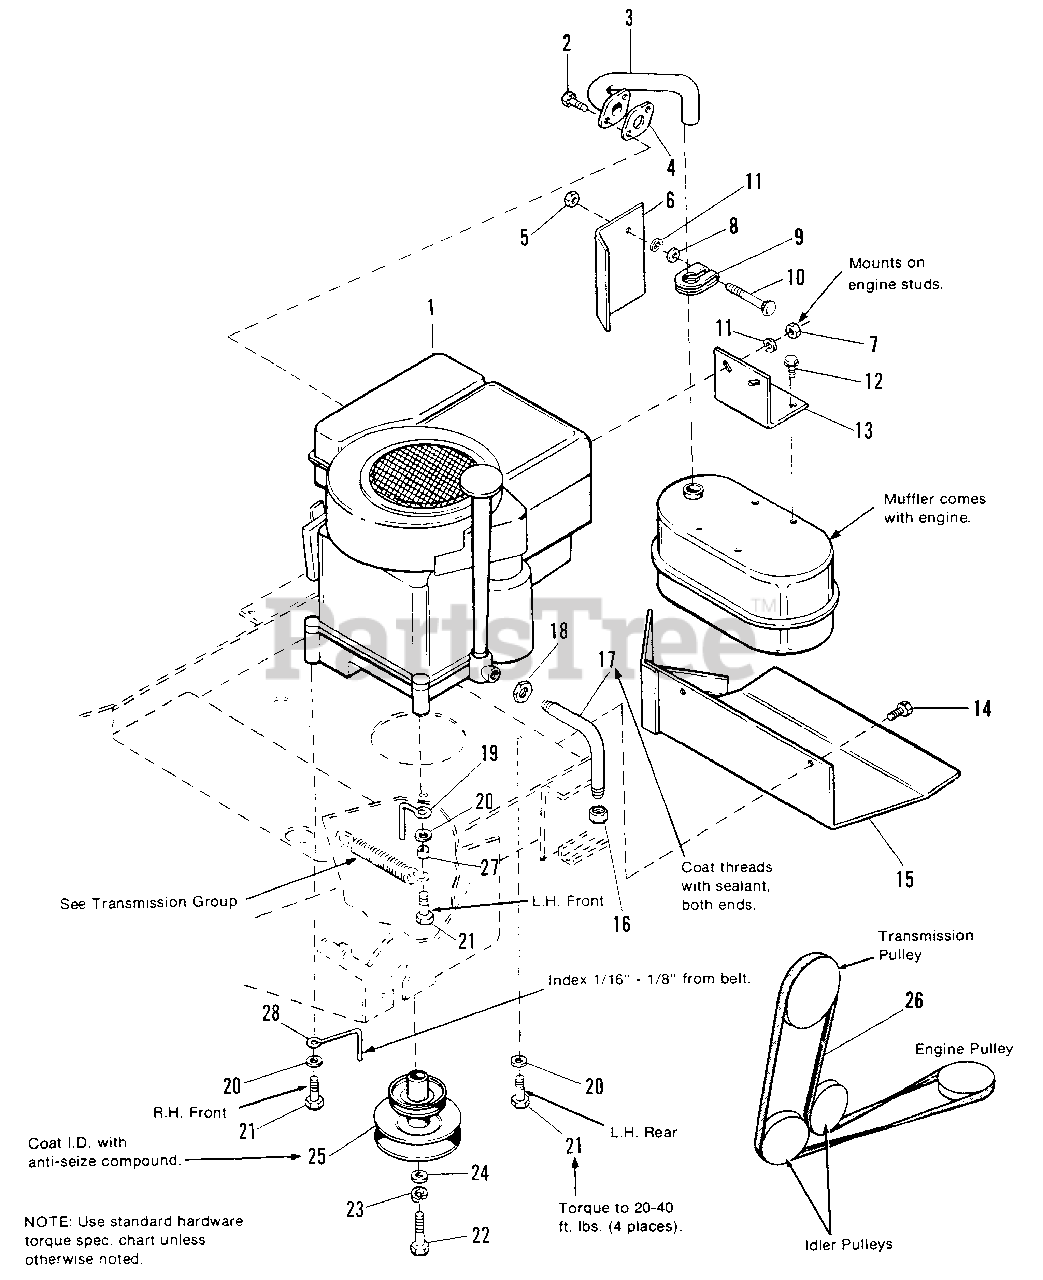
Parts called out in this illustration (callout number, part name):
1	ENGINE, 12 HP (Briggs & Stratton) (Includes muffler)
2	SCREW, Whizlock, 5/16-18 x 3/4 (12 HP only)
3	PIPE, Exhaust
4	GASKET, Muffler
5	LOCKNUT, 5/16-18
6	SHIELD, Heat (Muffler)
7	NUT, Hex, 5/16-18
8	WASHER, Plain, 5/16
10	BOLT, Carriage, 5/16-18 x 2-3/4
11	LOCKWASHER, 5/16
12	SCREW, Taptite, 1/4-20 x 5/8
13	BRACKET, Muffler
14	SCREW, Taptite, 5/16-18 x 1/2
15	HEAT SHIELD ASSY.
16	CAP. Hex, 3/8
17	DRAIN Oil
18	LOCKNUT, Conduit, 3/8
20	WASHER, 3/8
21	SCREW, Taptite, 3/8-16 x 1-1/2
22	CAPSCREW, Hex, 7/16-20 x 1-1/2
23	LOCKWASHER, 3/8
24	WASHER, 3/8
25	PULLEY ASSY., Engine
26	BELT, Transmission Drive
